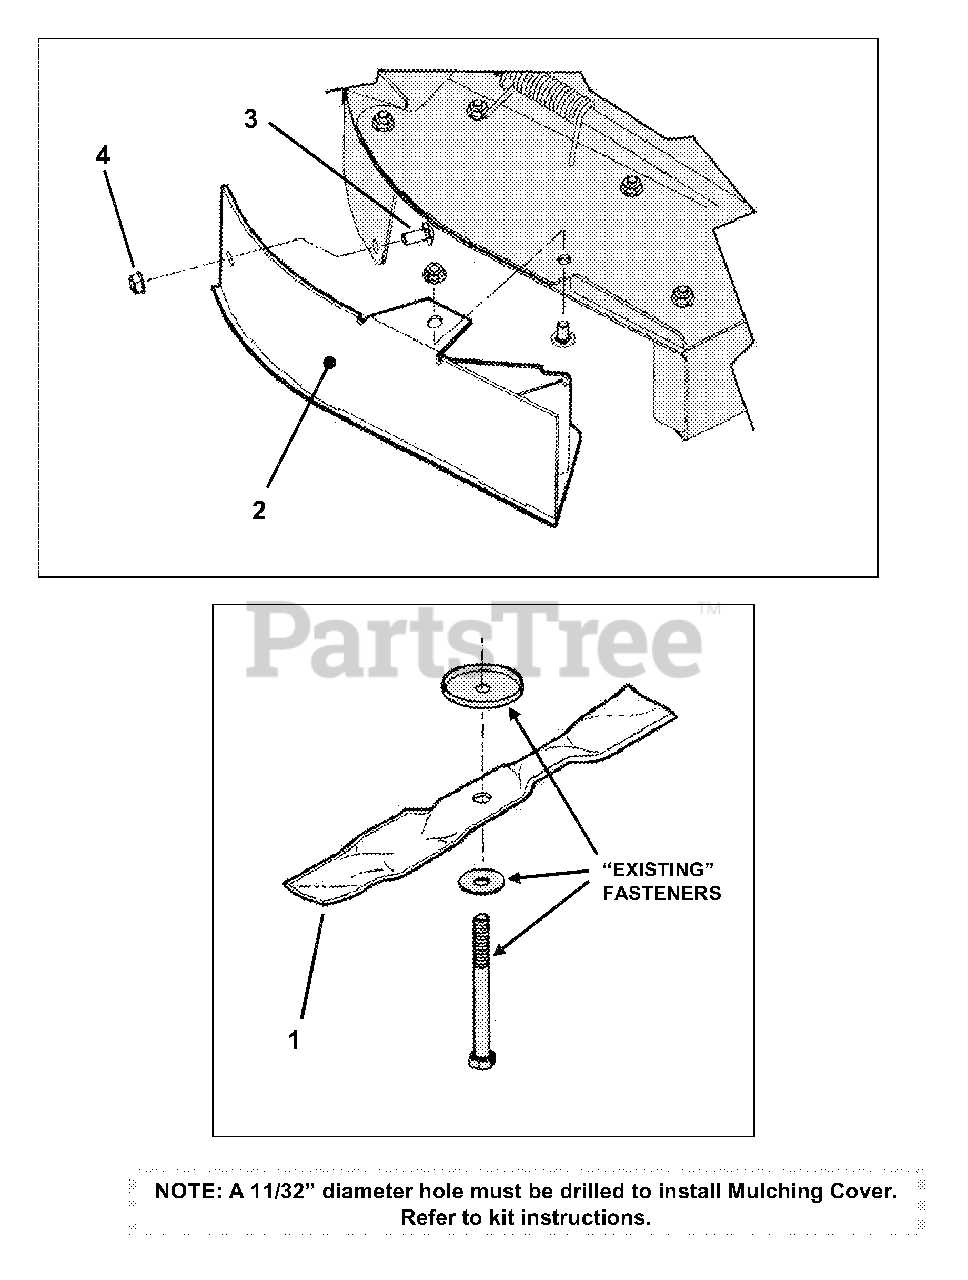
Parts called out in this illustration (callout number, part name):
1	BLADE, Ninja (Quad Edge, 5/8" Hole, 16-12' Length)
1	BLADE, Mulching (Positive Wave, 5/8" Hole, 16-1/2" Length)
2	WELDMENT, Mulching Cover
3	BOLT, 5/16-18 x 3/4" Short Neck Carriage, Grade 5
4	NUT, 5/16-18 Hex Flange Lock, Grade 5
